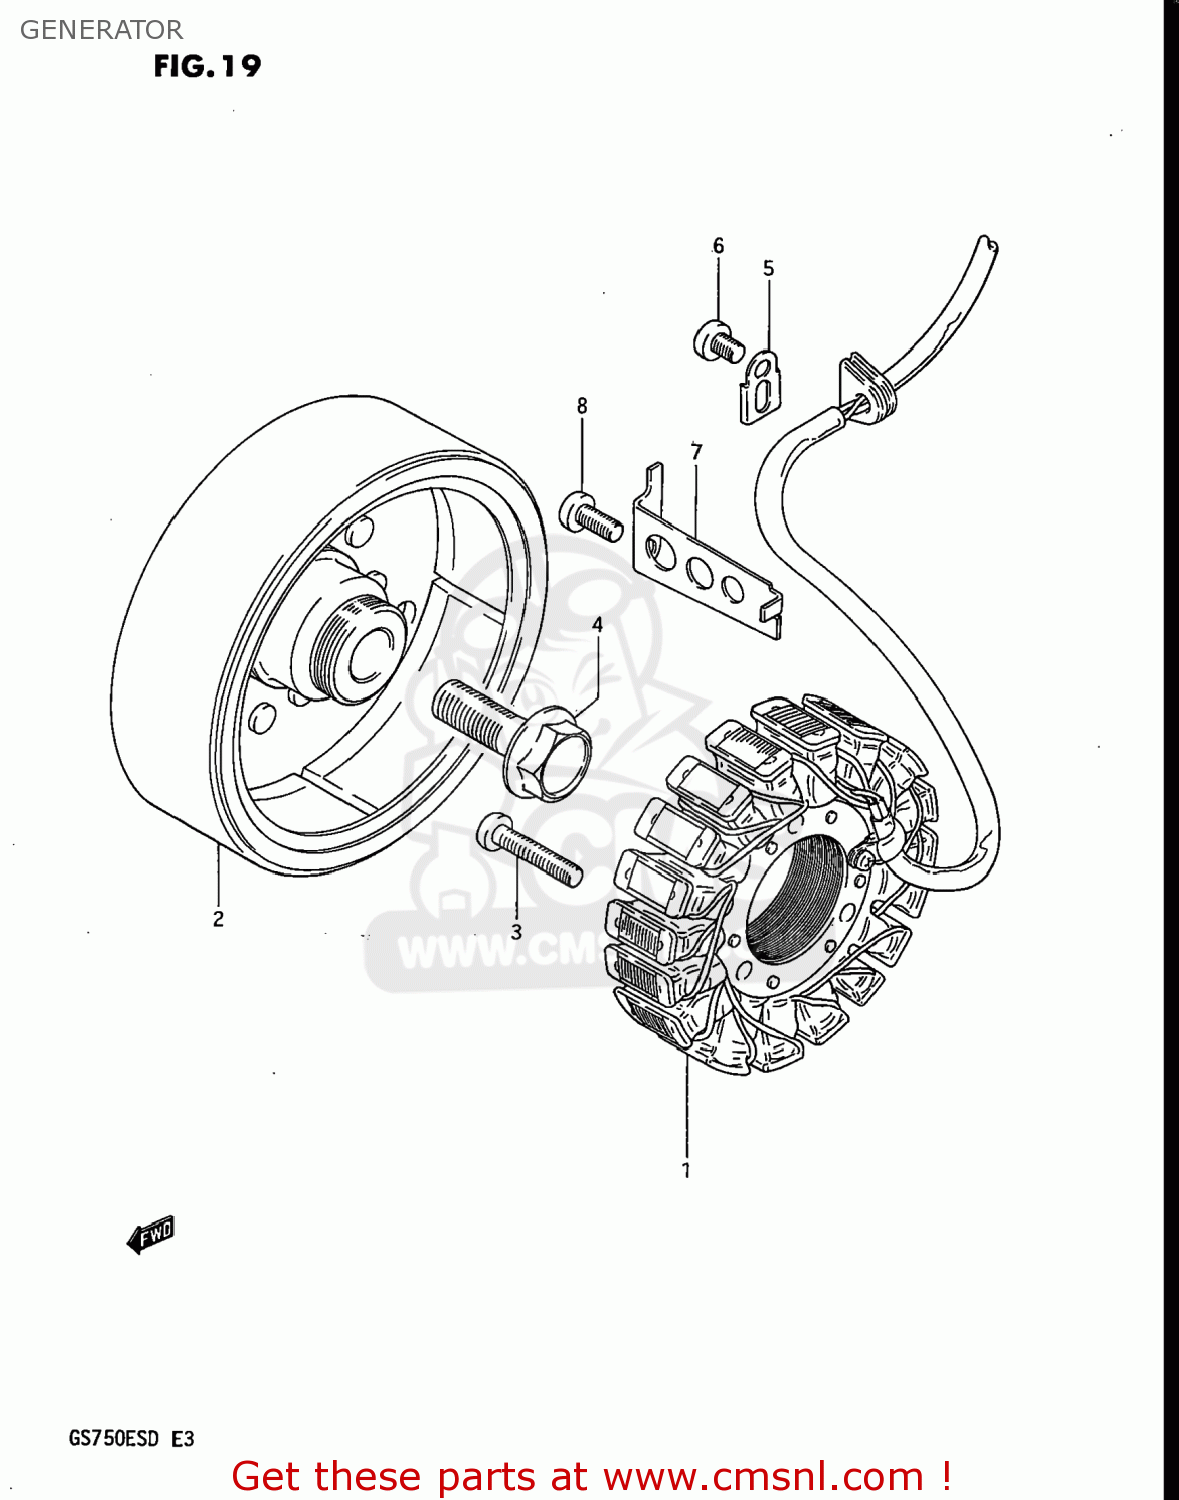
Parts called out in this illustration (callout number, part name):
1	STATOR ASSEMBLY
2	ROTOR ASSEMBLY
3	SCREW 6X30
4	BOLT(14X43)
5	CLAMP,GENERATOR LEAD WIRE
6	SCREW
7	CLAMP,GENERATOR LEAD WIRE
8	SCREW
